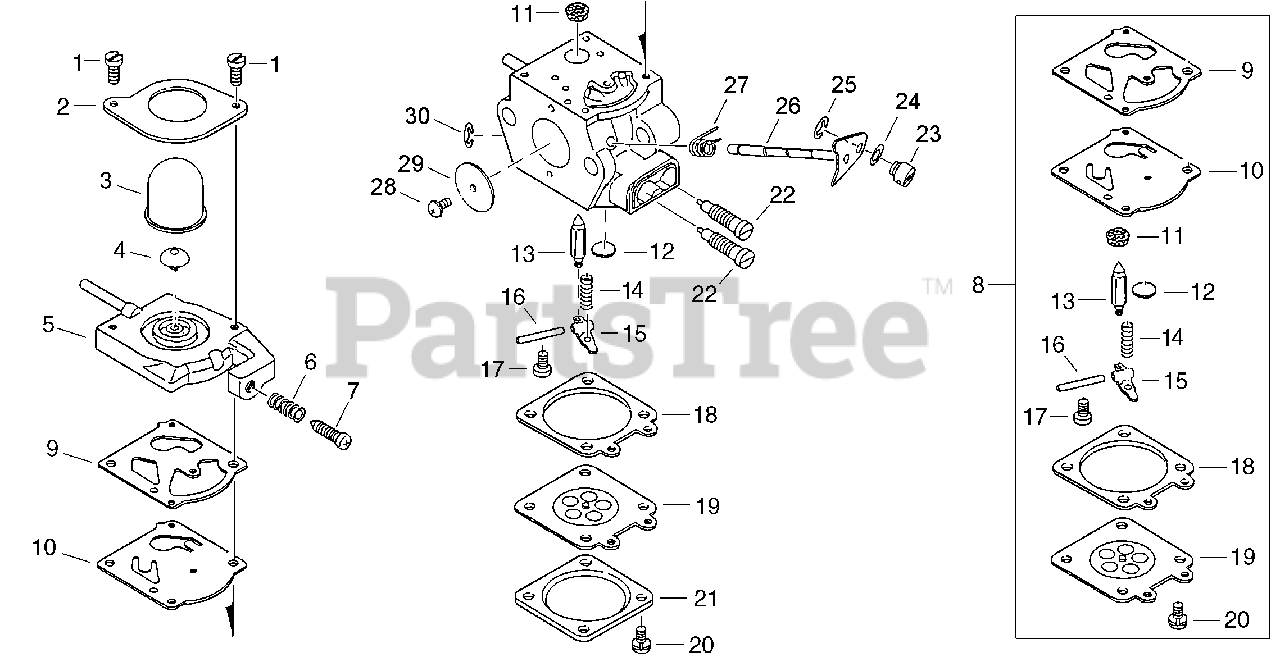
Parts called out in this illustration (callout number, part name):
1	SCREW, PUMP COVER
2	RETAINER, PURGE BULB
3	BULB, PURGE
4	VALVE, CHECK
5	BASE, PURGE
6	SPRING, IDLE ADJUST
7	SCREW, IDLE ADJUST
8	REPAIR KIT
9	GASKET, PUMP
10	DIAPHRAGM, PUMP
11	STRAINER
12	PLUG, WELCH
13	VALVE, INLET NEEDLE
14	SPRING, METERING LEVER
15	LEVER, METERING
16	PIN, METERING LEVER
17	SCREW, METERING LEVER PIN
18	GASKET, METERING
19	DIAPHRAGM, METERING
21	COVER, METERING
22	NEEDLE - MIXTURE
25	RING, RETAINING
26	SHAFT, THROTTLE
27	SPRING, THROTTLE RETURN
29	VALVE, THROTTLE
30	RING, RETAINING
